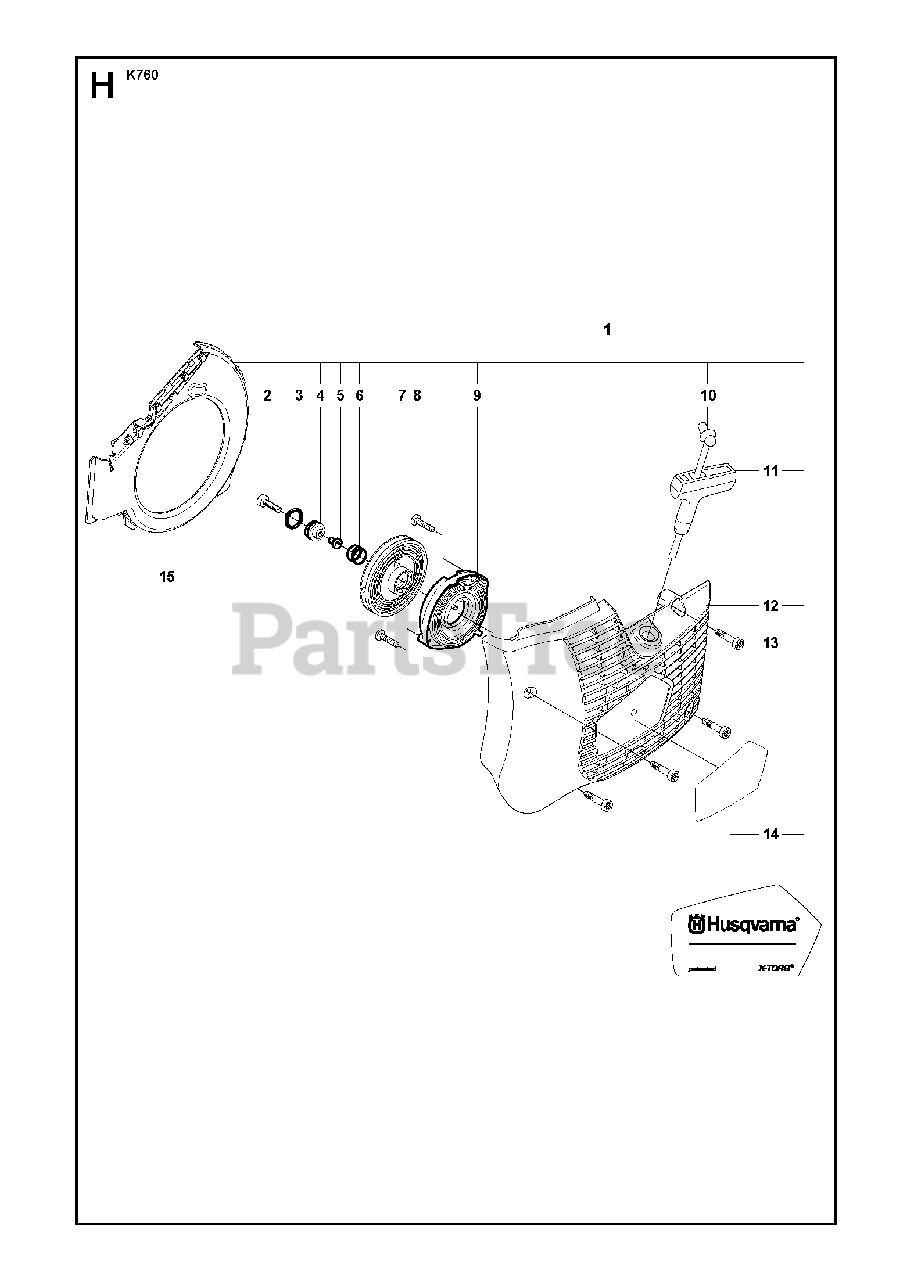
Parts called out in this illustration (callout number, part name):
1	STARTERIncl. 2 - 15
2	SCREW ITXSCT
5	SPACING SLEEVE
6	COMPRESSION SPRING
7	STARTER PULLEY
8	SCREW CCRPANT
9	RECOIL SPRING
10	STARTER CORD50 m
11	STARTER HANDLE
12	STARTER COVER
13	SCREW ITXSCM
15	AIR CONDUCTOR
